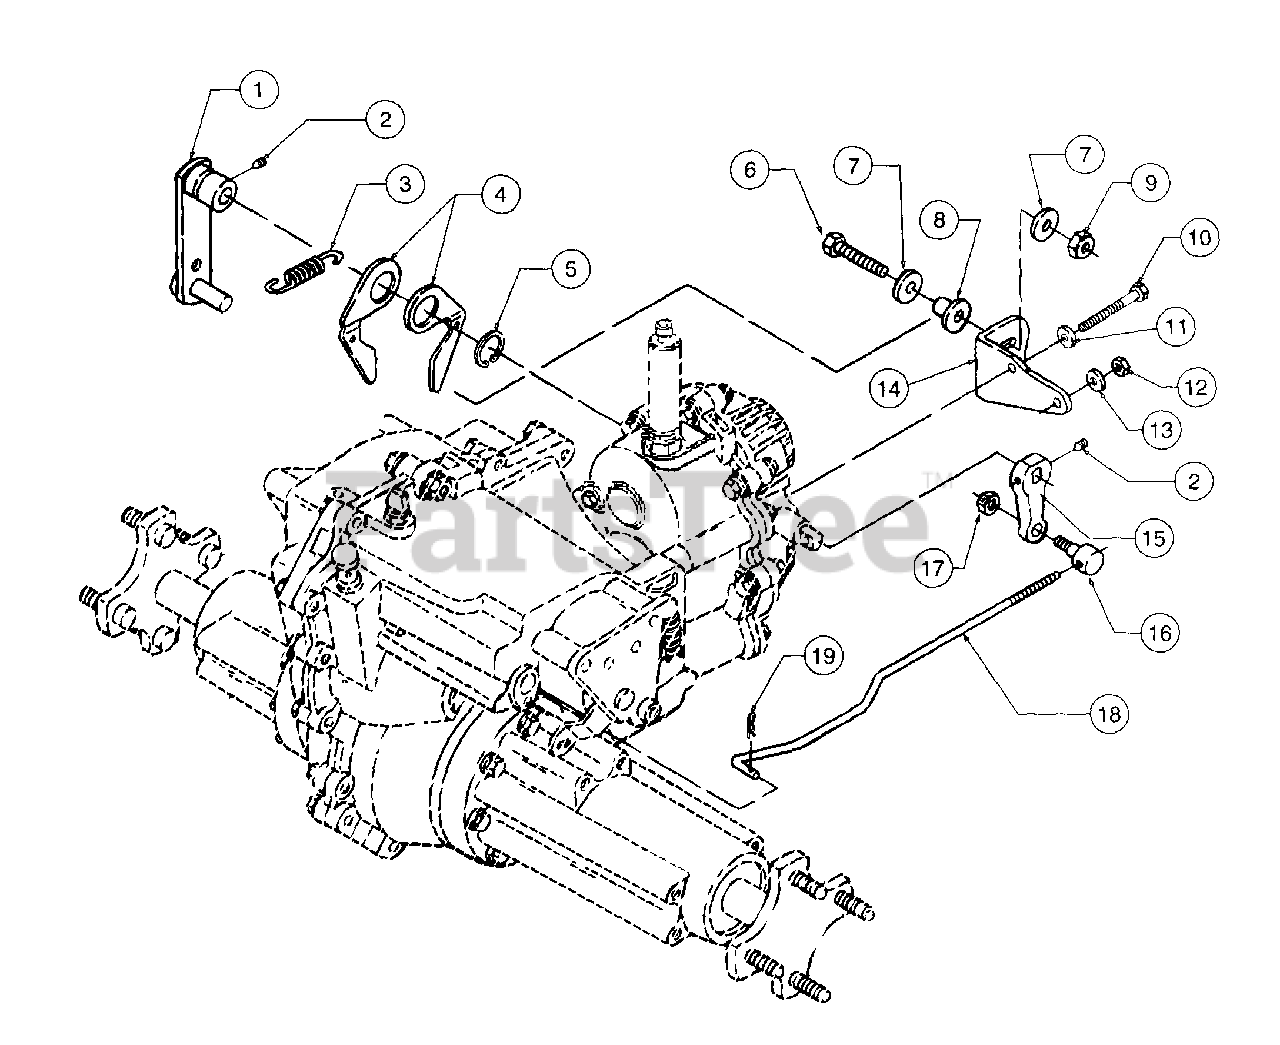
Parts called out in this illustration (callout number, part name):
1	Arm Assy, Control
2	Screw w/Patch, Set
3	Spring, Extension, .477 OD x 1.68 Lg
4	Arm, Neutral
5	Ring, Snap, .875 Shaft
6	Screw, Hex Cap, 1/4-20 x 1.25
7	Washer, Flat, .25 x .93 x .120
8	Spacer, Centering
9	Nut, Hex Top Lock, 1/4-20
10	Screw, Hex Cap, 5/16-18 x 4.0
11	Washer, Lock, 5/16
12	Nut, Hex Center Lock, 1/4-20
13	Washer, Flat, .25 x .62 x .052
14	Bracket, 6-Speed Neutral
15	Arm, Clutch/Brake
16	Ferrule, 5/16-24 Thrd
17	Nut, Hex Center Lock Jam, 5/16-24
18	Rod, Shift Interlock
19	Pin, Internal Cotter
